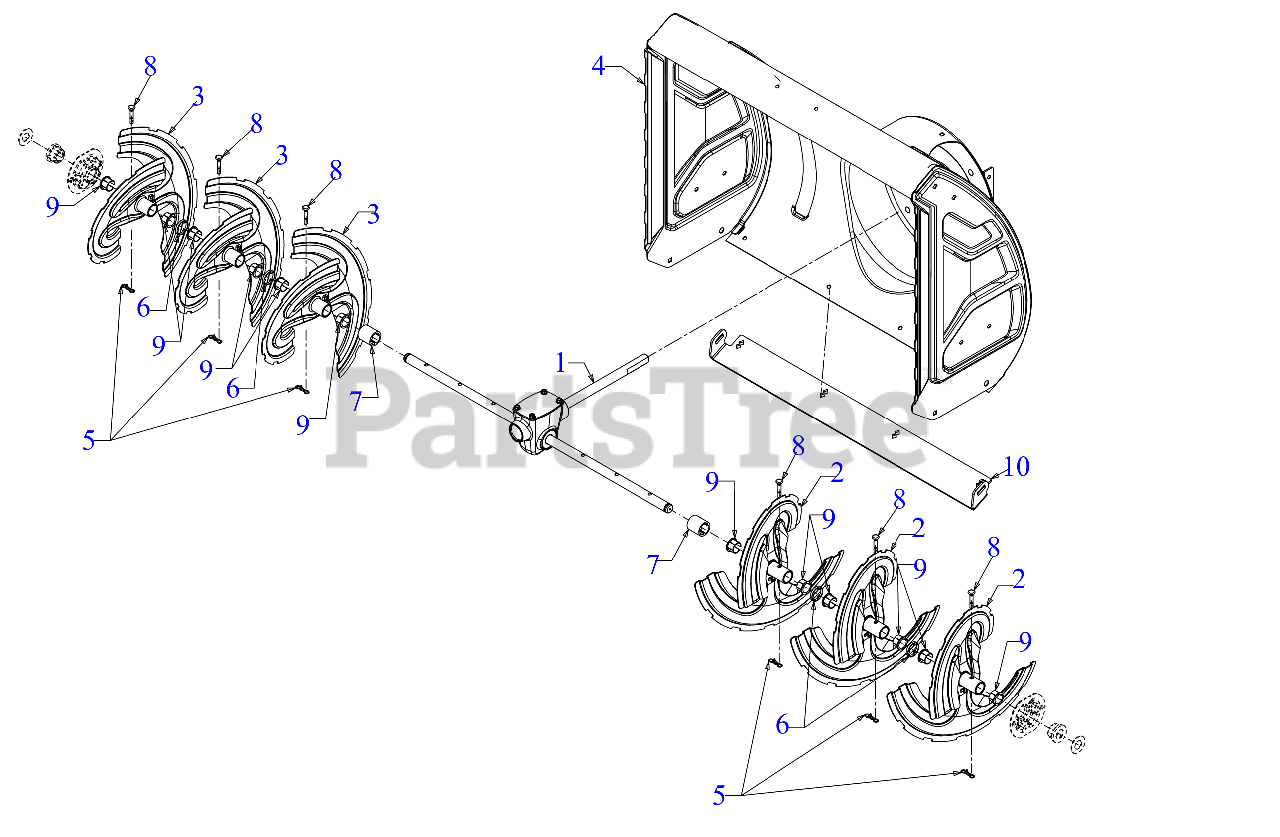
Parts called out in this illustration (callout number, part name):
1	30" AUGER GEARBOX ASSEMBLY
4	30" AUGER HOUSING ASSEMBLY HD W/LED
5	BOW TIE COTTER PIN 1/4-5/16
6	SPCR 1.25 OD x 75IDX2.00LG
7	SPACER 1.25OD x .75ID x 1.312 LG
8	SHEAR PIN .25 x 1.50 GR2
9	FLANGE BUSHING
